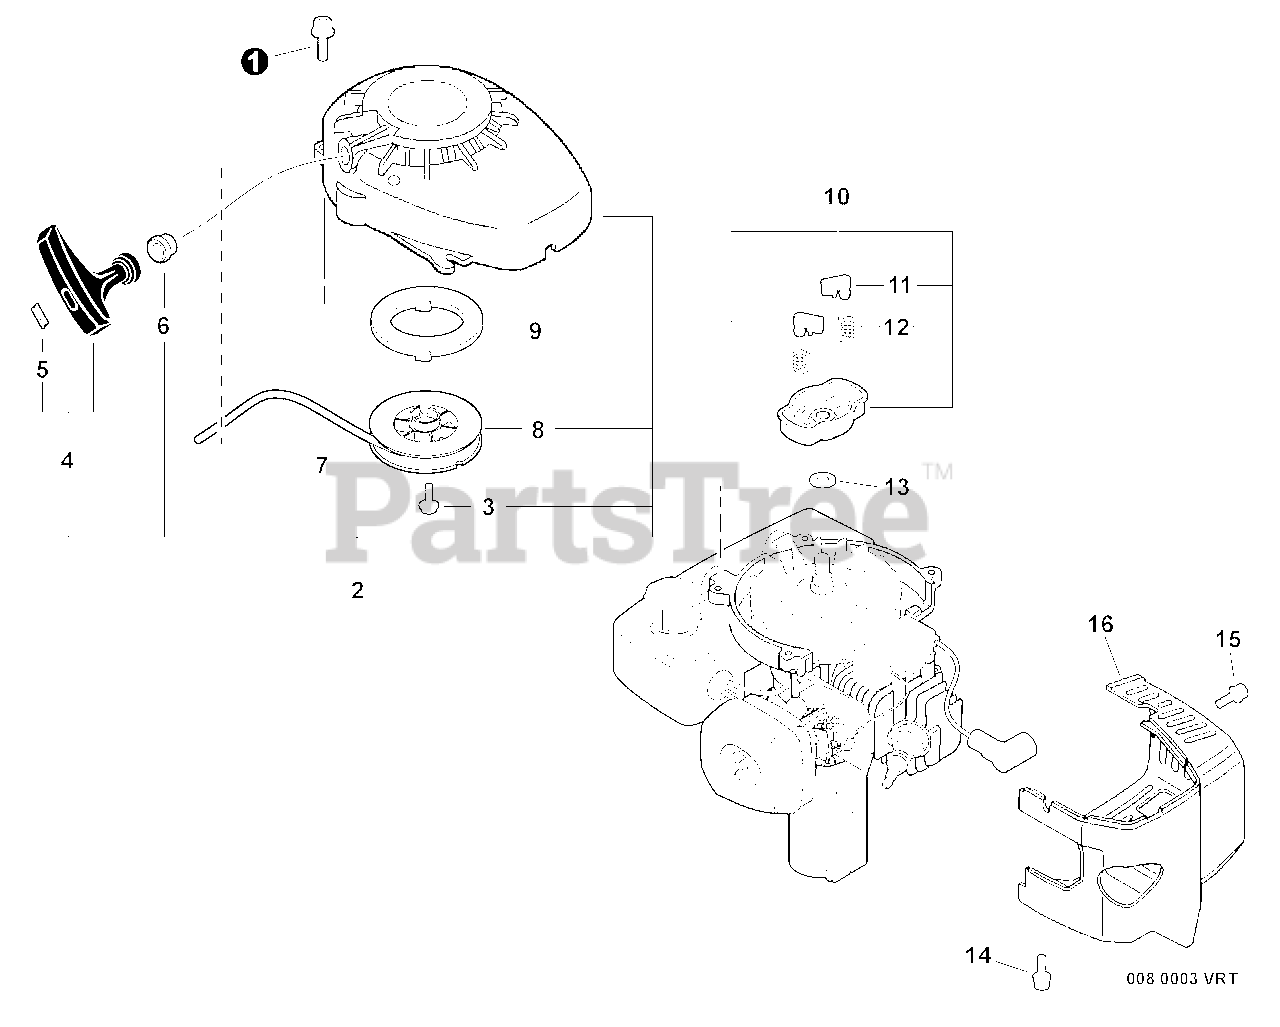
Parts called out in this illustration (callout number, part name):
1	SCREW - 4X16
2	STARTER ASSY
4	GRIP, STARTER
5	RETAINER, ROPE
6	GUIDE, ROPE
7	ROPE, STARTER - 3X890
8	REEL, ROPE
9	SPRING, REWIND
10	STARTER PAWL ASSY
11	PAWL, STARTER - BLACK
12	SPRING, RETURN
13	LOCKWASHER - 8
14	SCREW - 4X18
15	SCREW - 4X8
16	COVER, ENGINE - ORANGE
